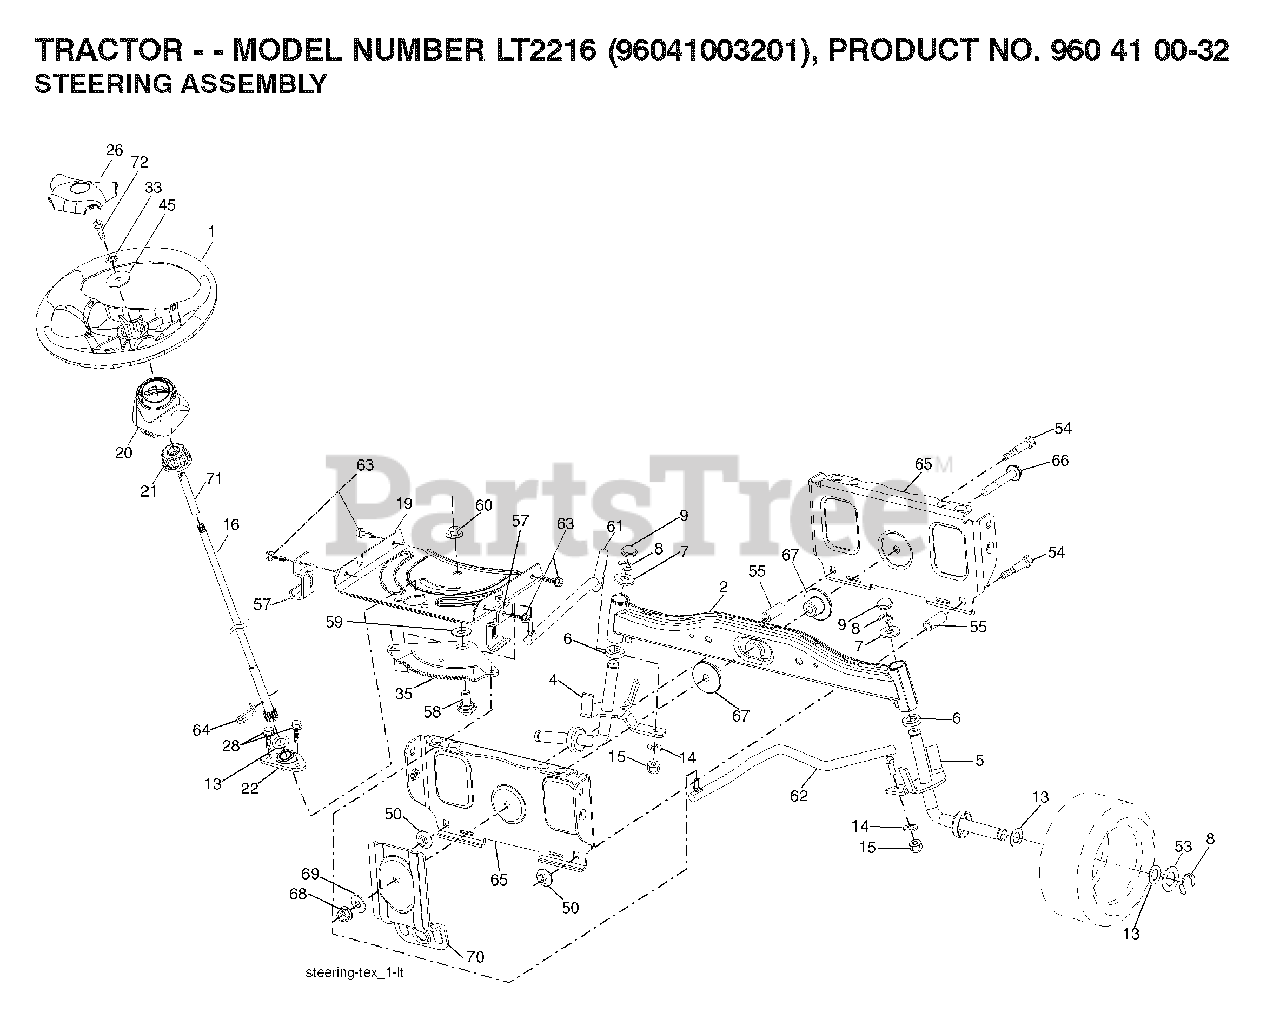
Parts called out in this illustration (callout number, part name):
2	AXLE.HALF.ASM.WELDED
4	SPINDLE.WELDED.LH.15"TEX
5	SPINDLE.WELDED.RH.15"T
8	RING CLIP
9	CAP.SPINDLE
14	WASHER, LOCK 3/8
15	NUT CROWNLOCK 3/8-24
16	SHAFT STEERING
19	PLATE.STEER.DDL.NLT/NG
20	BOOT STEERING BLACK
21	ADAPTER, WHEEL STNG..
22	BUSHING.ASM.STEERING.A
26	INSERT.CAP.STRG.WH.BLACK
28	SCREW, 3/8-16X3/4
33	LOCKWASHER
35	GEAR.SECTOR.PLATE.DDL.
45	WASHER.11/32
50	NUT LOCK FLG 3/8-16 UNC
53	WASHER.HARDENED
55	SPACER.BRACE.AXLE
57	BRACKET.UPSTOP.TEX
58	BOLT.SHOULDER.SECTOR.P
59	WASHER.THURST.SECTOR.S
60	NUT FLANGE LOCK 5/8-11
61	DRAGLINK.LH.BALLSTUD.D
62	DRAGLINK.RH.BALLSTUD.D
63	SCREW
64	RETAINER.CLIP.SPRING.S
65	BRACE.AXLE.FRONT.NLT/N
66	BOLT HEX FGHD 7/16-14 X 3 SERR
67	BUSHING.PM.FRONT AXLE
68	NUT.LOCK.FLANGE.7/16
69	WASHER.1.5X.505X.118
70	BRKT.DECK.SUSPENSION.F
71	SHAFT EXTENSION STEERING
72	BOLT YT
74	BRNG T
